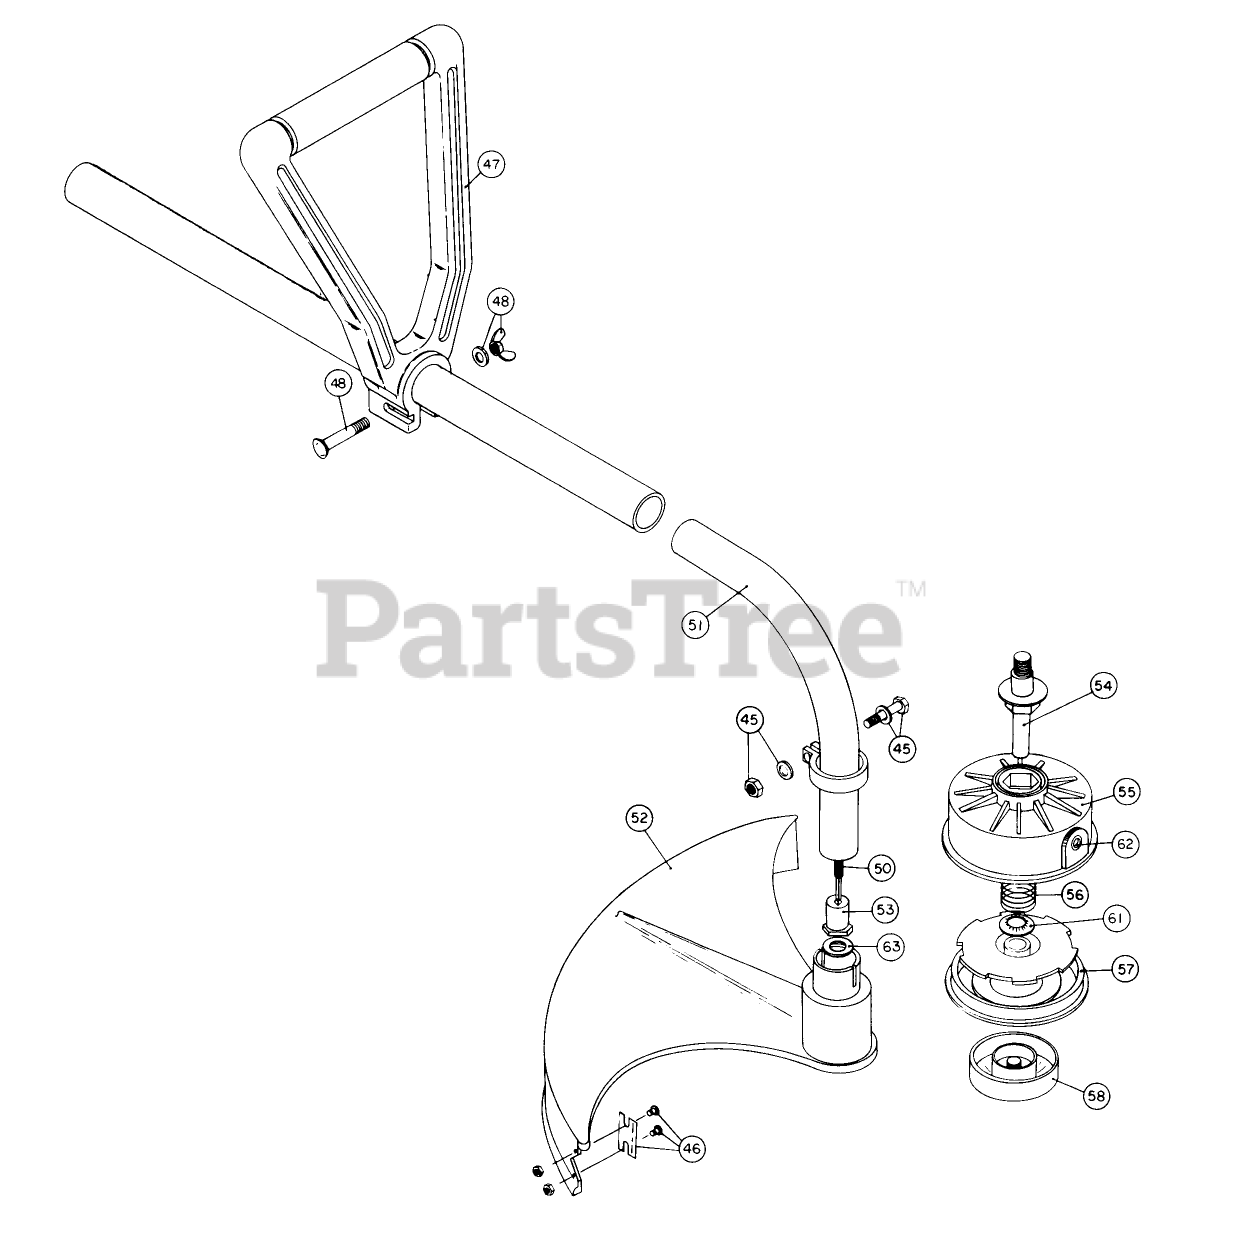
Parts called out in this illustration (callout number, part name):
46	BLADE ASM
53	SQUARE DRIVE NUT
57	REEL - INNER
61	RETAINER WASHER
